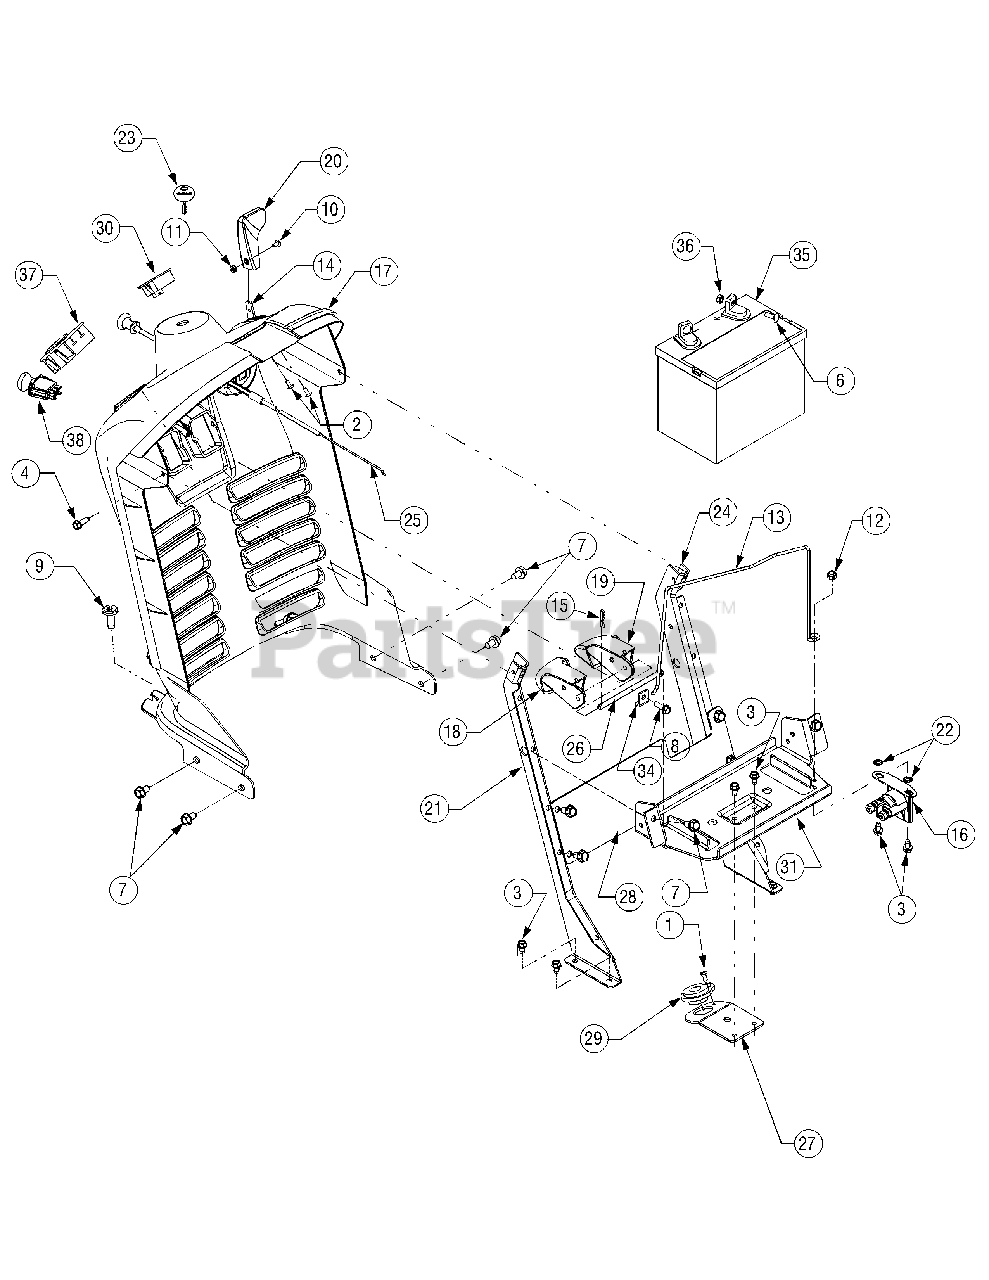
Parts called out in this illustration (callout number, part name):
1	Screw, #10-16 x .625
2	Screw, #10-24 x .375
3	Screw, Self-tapping, 1/4-20, 0.500
4	Screw, Hex. 1/4-20 x .75
5	Screw, Hex, 5/16-18, .875 Gr5
6	Screw, Carriage, 1/4-20, .75,
7	Screw, Hex, 5/16-12 x .75
8	Screw, 1/4-15, 0.750
9	Screw, Torx Hd. Tapp. 5/16-18 x .75
10	Screw, Machine, #8-32, 0.375, Trus Phillips
11	Nut, 8-32
12	Nut, Nylon Lock, 1/4-20
13	Hold-down Rod, Battery
14	Control, Throttle, 27.4 (LT1042 & LT1045)
14	Control, Throttle, 38.0 (LT1046 & LT1050)
15	Internal Cotter Pin, .072 x 1.13
16	Solenoid, 12V, 100 Amp
17	Dash
18	Lever, Dash, Cruise
19	Lever, Dash, Brake
20	Knob, Throttle Control
23	Ignition Key, Plastic
23	Ignition Key, Metal
25	Control, Choke, 24.0 (LT1042 & LT1045)
25	Control, Choke, 37.5 (LT1046 & LT1050)
26	Rod, .250 Dia x 4.25 Lg.
30	Monitor, Systems Indicator / Hour Meter
35	Battery, 190 CCA (LT1042 & LT1045)
35	Battery, 235 CCA (LT1046 & LT1050)
36	Nut, Sems, 1/4-20
37	Switch Module, Ignition
38	Switch, PTO, Yellow
